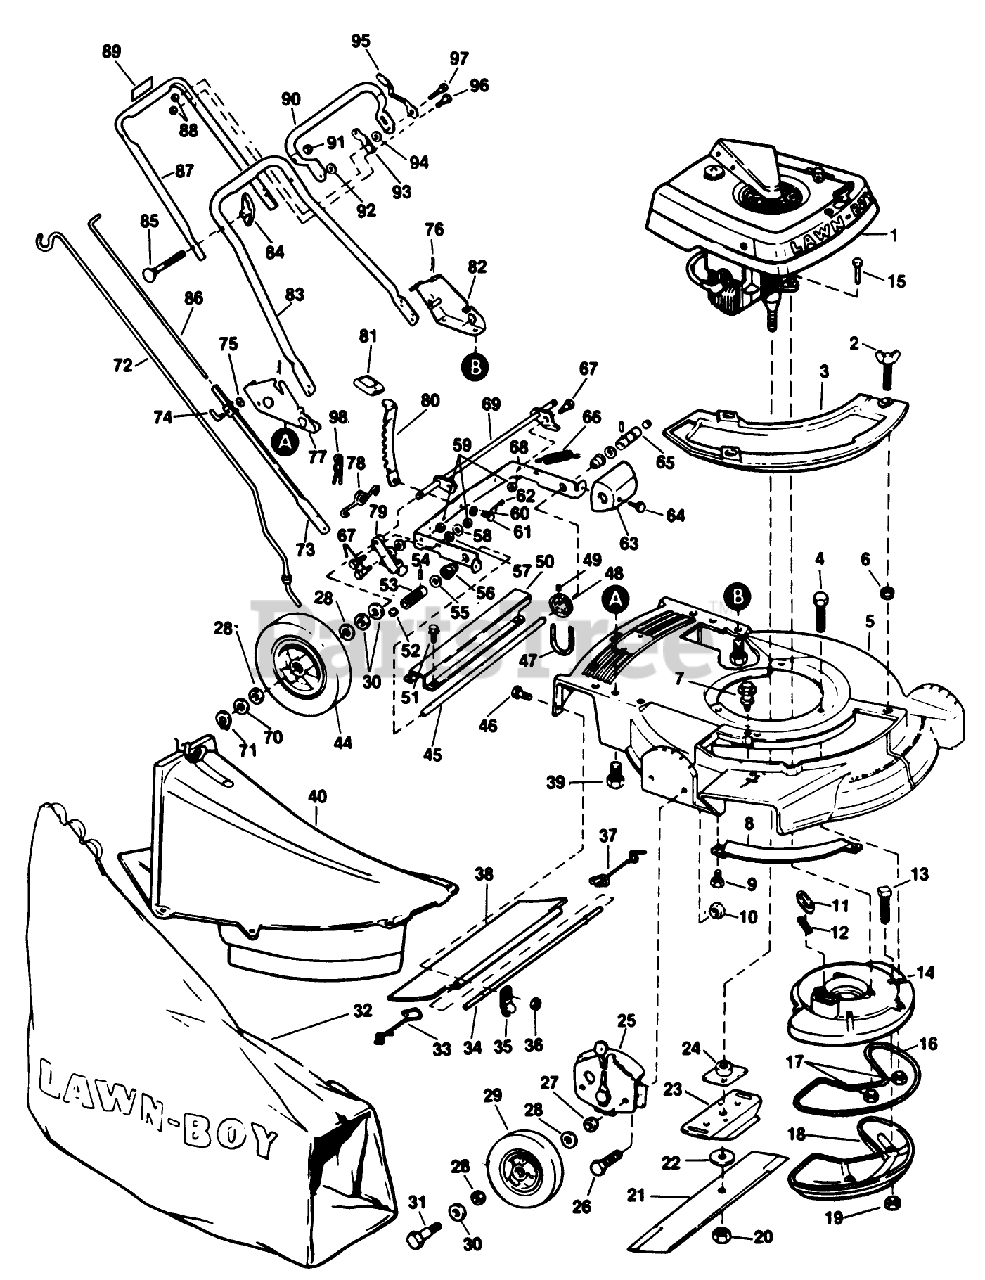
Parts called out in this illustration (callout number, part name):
1	See Note #2 at bottom of this page.
2	WING SCREW LAWRE
4	SCREW
8	BAR-TOE
10	NUT-LOCK F
11	SLEEVE
12	GASKET S
13	SCREW
17	NUT-LOCK F
20	NUT-BLADE
22	WASHER
24	PLATE AND COLLAR ASM
27	WASHER WROUGHT
28	WASHER
29	WHEEL & TIRE KIT
30	SPACER
31	BOLT WHEEL
32	89802 LB WHOLE GOODS
33	SPRING;TRAILING SHIELD RH
34	ROD 21" ADVANCE
35	CLAMP ROD KMC
36	LOCKNUT E
37	SPRIG T/SHLD ASOC
39	SCREW
45	DRIVE SHFT TAG AY
47	V-BELT
51	SCREW F
52	GREASE PLUG
54	PIN
58	WASHER S
59	STOP NUT
60	WASHER SPRING LAR
61	PIN
63	GUARD
66	SPRING
67	BOLT RB&W
70	SPACER
71	RET RING
72	ROD GRASSBAG
76	HAIR PIN
78	SPRING N.A.S
80	LEVER
81	KNOB
84	LOCKNUT E
85	SCREW
86	ROD CONTROL
88	LOCKNUT E
92	WASHER M
95	KNOB & SPRING
97	BOLT RB&W
